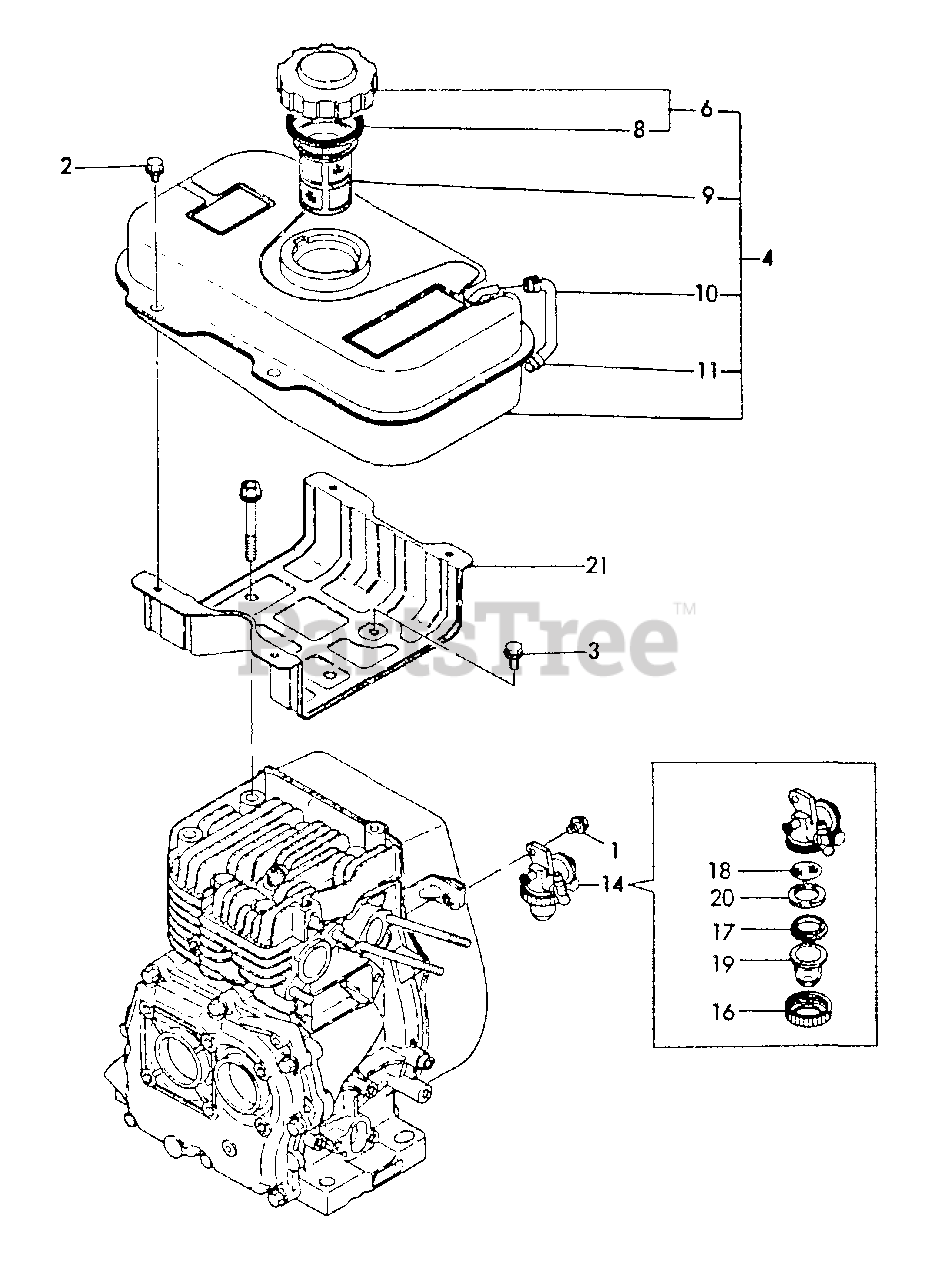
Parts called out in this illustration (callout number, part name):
1	BOLT - 6X8 -- PLATED
2	BOLT - 6X10 -- PLATED
3	BOLT - 6X8 -- PLATED
4	FUEL TANK ASSY
6	CAP ASSY
8	GASKET
9	STRAINER, FUEL
10	PIPE, GAUGE
11	CLAMP, HOSE - 9
14	FUEL COCK ASSY
16	RETAINER
17	GASKET
18	FILTER, FUEL
19	BOWL, STRAINER
20	PLATE
21	BRACKET, FUEL TANK
